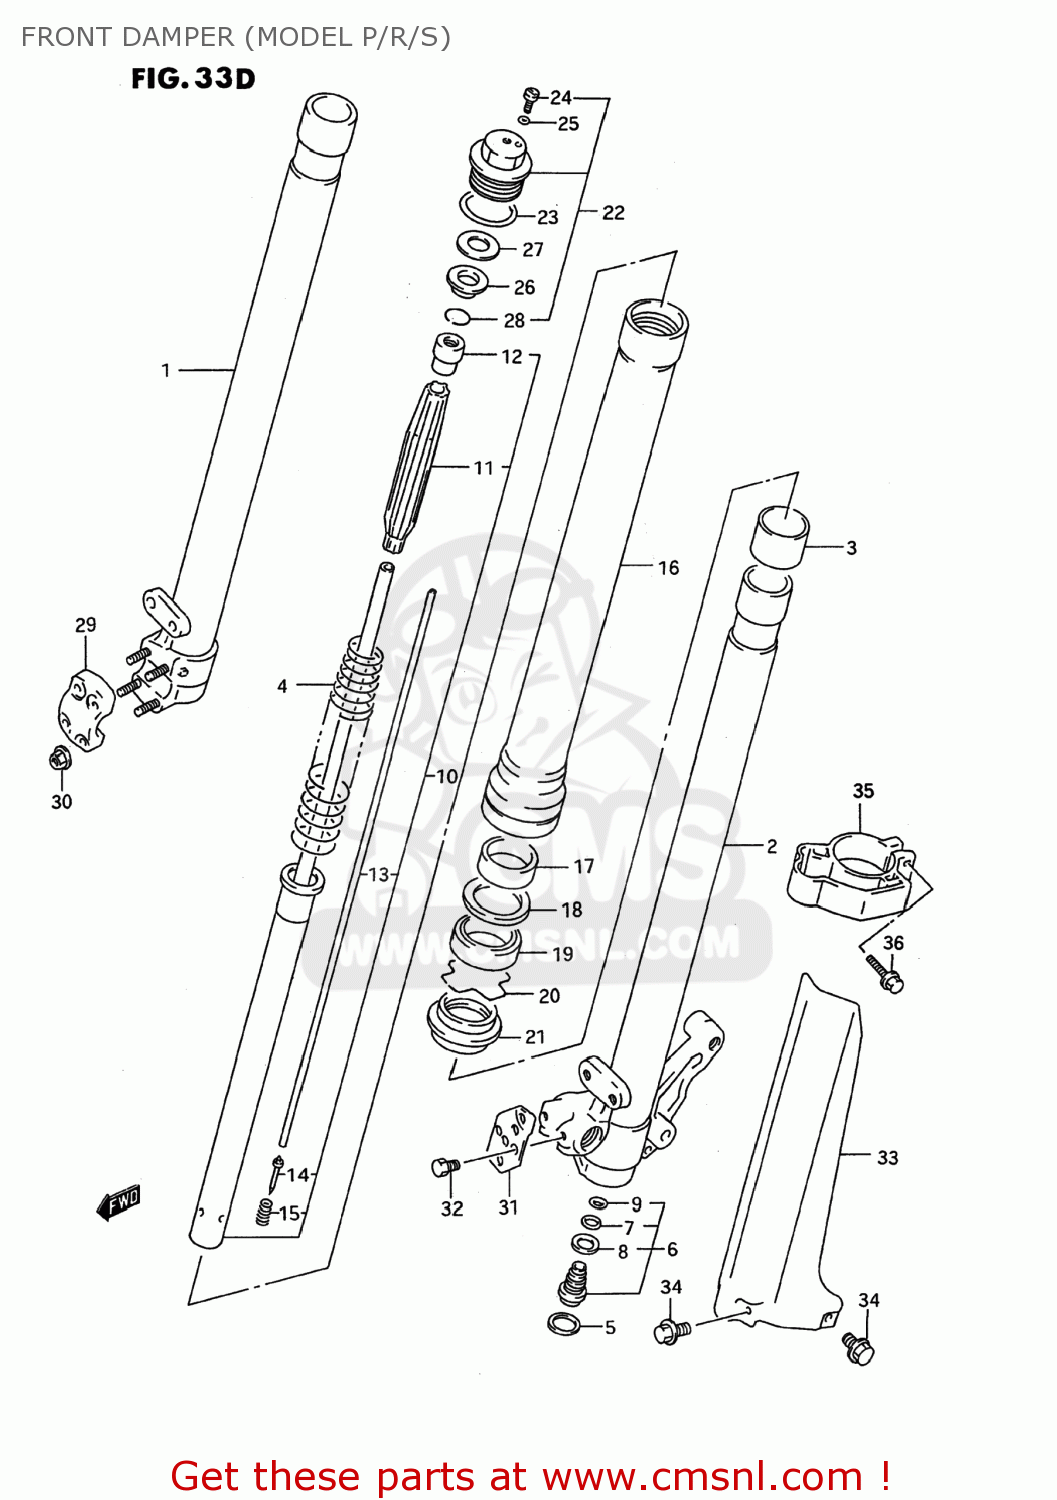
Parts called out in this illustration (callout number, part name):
1	TUBE,INNER,RIGHT
2	TUBE,INNER,L
3	BUSH,SLIDE
4	SPRING,MAIN
5	RING,CTR BOLT STOPPER
6	BOLT ASSEMBLY,CENTER
7	O RING,CTR BOLT
8	GASKET (NAS)
9	O RING,CTR BOLT UPR
10	CYLINDER
11	GUIDE,PUSH ROD SPRING
12	NUT,ROD
13	ROD,PUSH
14	NEEDLE
15	SPRING,PUSH ROD
16	TUBE,OUTER
17	BUSH,GUIDE
18	SPACER,SEAL
19	SEAL,OIL
20	RING,OIL SEAL STOPPER
21	SEAL,DUST
22	BOLT ASSY,FORK
23	O RING
24	BOLT,PLUG
25	O RING
26	SEAT,SPRING
27	WASHER,THRUST
28	RING,STOPPER
29	HOLDER,AXLE,R
30	NUT
31	GUIDE,HOSE,L
32	BOLT
33	PROTECTOR,FORK,R
34	BOLT,PROTECTOR(6X10)
35	GUIDE,FORK PROTECTOR
36	BOLT,PROTECTOR GUIDE,6
